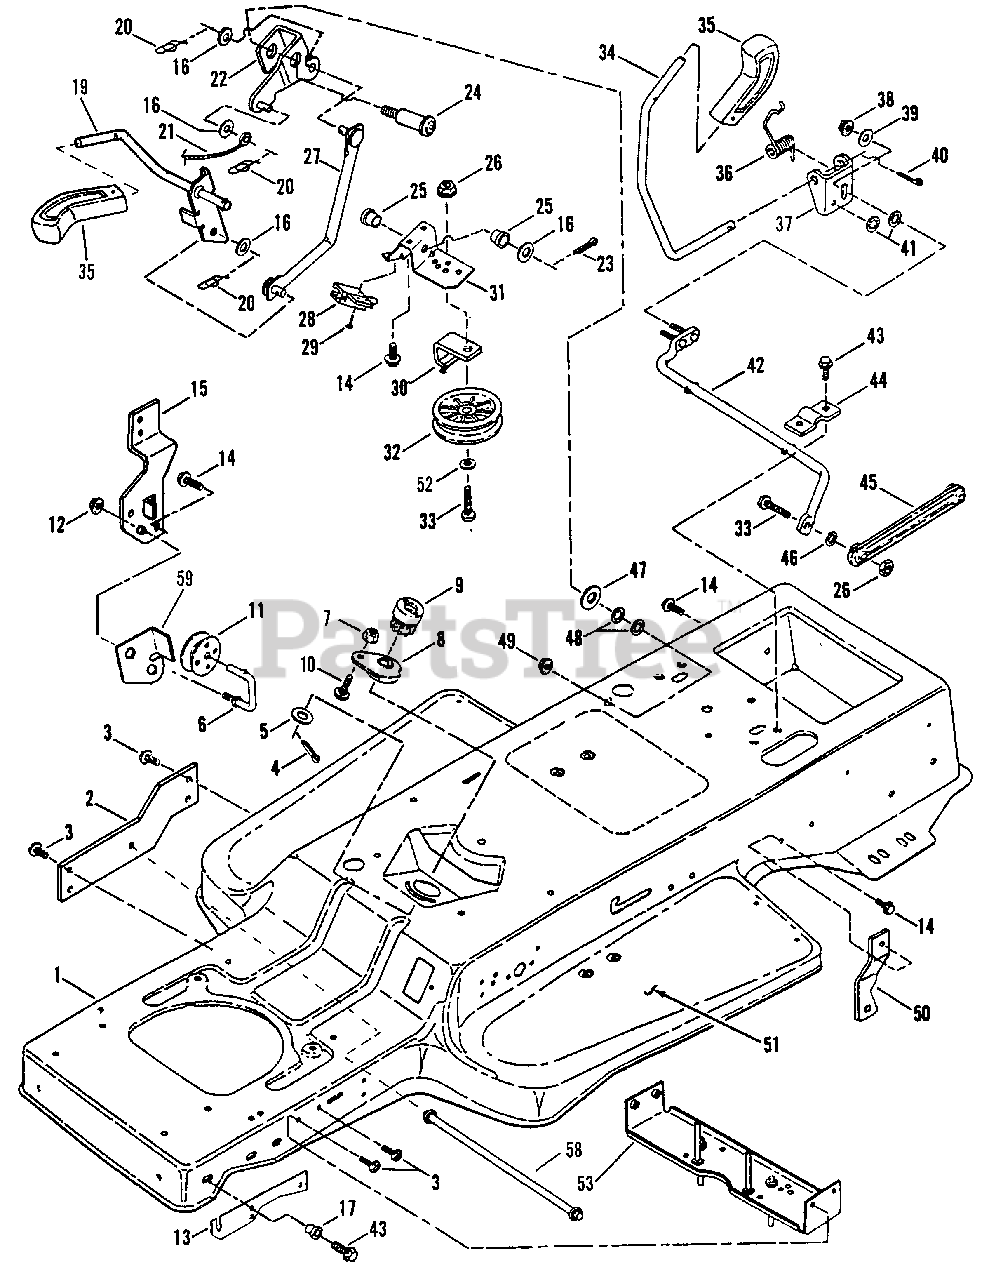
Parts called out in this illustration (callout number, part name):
1	FRAME, Tractor
2	BRACE, Frame
3	SCREW, 5/16-18 x 5/8" Truss Head (Torx)
4	PIN, 1/8 x 3/4" Cotter
5	WASHER, 1/2 Shim
6	ROD, Spool Pivot
7	NUT, 1/4-20 Hex Flange Lock, Grade 5
8	ASSEMBLY, Steering Adjuster
9	GEAR, Steering Pinion
10	BOLT, 1/4-20 x 5/8" Short Neck Carriage, Grade 5
11	SPOOL
12	NUT, 5/16-18 Hex Flange Lock, Grade 5
13	BRACKET, Hood Pivot
14	SCREW, 5/16-18 x 1-1/4" Self-Tapping
15	BRACKET, Axle/Spool
16	WASHER, 7/16" I.D. Flat
17	BUSHING, Flange
19	LEVER, PTO
20	PIN, 3/8" Self Locking Cotter
21	CABLE, Blade 13.95"
21	CABLE, Blade 14.7"
21	CABLE, Blade 28.375"
21	CABLE, Blade 27.875"
22	BELLCRANK, PTO
23	PIN, 3/32 x 3/4" Cotter
24	BOLT, 1/2-13 x 2-11/32" Shoulder
25	BUSHING 920
26	NUT, 3/8-16 Hex Center. Lock, Gr. 5
27	ROD, PTO Link
28	SWITCH
29	SCREW, #10-24 x 1/2" Hex Washer Self-Tap (Torx)
30	GUIDE, Belt
31	SUPPORT, PTO Lever
32	PULLEY
33	SCREW, 3/8-16 x 1-1/2" Hex Head Cap, Grade 5
34	LEVER, Shift
35	KNOB, Deck Lift Lever
36	SPRING, Shift Lever
37	BRACKET, Shift Lever (Upper)
38	NUT, 1/4-20 Hex Nyloc
39	WASHER, 1/4 I.D Flat
40	PIN, 5/32 x 1" Cotter
41	WASHER, 1/4 Internal Tooth Lock
42	ASSEMBLY, Shift Lever (Lower)
43	SCREW, 5/16-18 x 1-1/4" Self-Tapping
45	LINK, Shift Lever
46	SPACER
47	WASHER, Thrust
48	WASHER, 1/2" Internal Tooth Lock
49	NUT, 1/2-13 Hex Flange Lock, Grade 5
50	BRACKET, Torque
51	PAD, Foot Sandpaper
51	PAD, Foot, Rubber Deluxe
52	WASHER, 3/8" Flat
53	* BRACKET, Belt Guide
58	GUIDE, Belt
59	GUIDE, Cable
